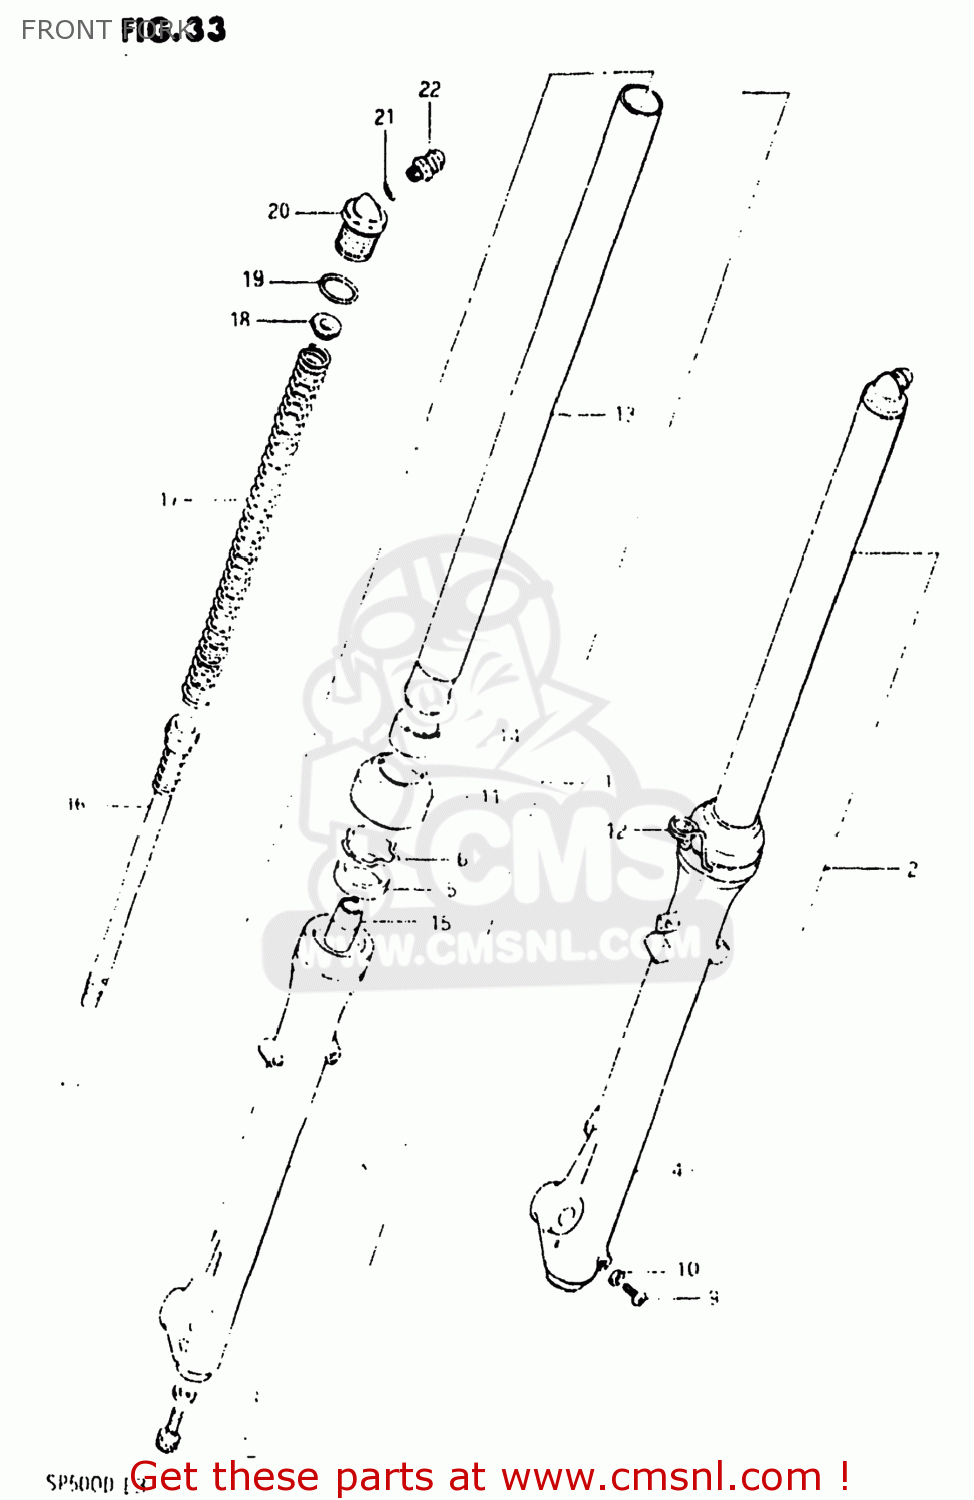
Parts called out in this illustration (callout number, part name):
1	DAMPER ASSEMBLY,RIGHT
2	DAMPER ASSEMBLY,LEFT
3	TUBE,OUTER,RIGHT
4	TUBE,OUTER,LEFT
5	OIL SEAL,FRONT FORK
6	7
7	BOLT,FORK CYLINDER(10X25)
8	GASKET (NAS)
9	SCREW
10	GASKET,DRAIN,PLUG (NAS)
11	SEAL,DUST
12	BAND,FRONT FORK COVER
13	TUBE,FORK,INNER
14	PISTON
15	PIECE,OIL LOCK
16	CYLINDER,FRONT FORK
17	SPRING,FRONT FORK
18	GUIDE,FRONT FORK SPRING C
19	O RING
20	BOLT,FORK
21	O-RING
22	VALVE,FRONT FORK AIR
